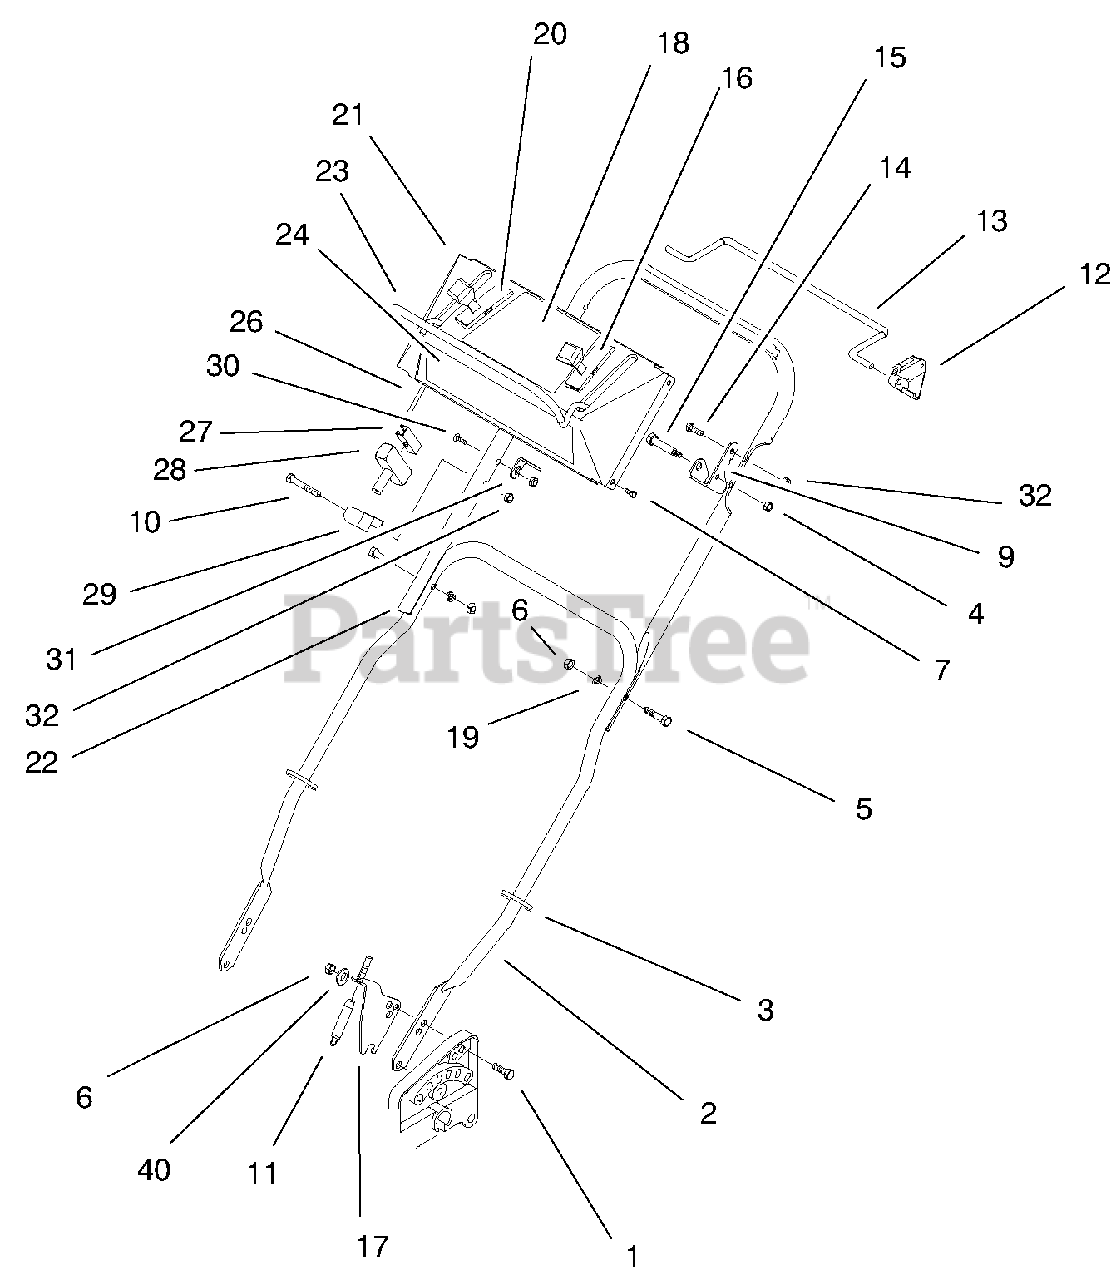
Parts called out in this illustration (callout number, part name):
1	Bolt-CARR
2	Handle Section-Lower
3	Tie Strap
4	Nut-Lock
5	Screw-HH
6	Nut-Lock
7	Screw-Phil
9	Bail Stop Bracket
10	Bolt-Hex
12	Stop-Pivot
13	Bail-Sp Control
14	Screw-HH
16	Throttle Cable
17	Bracket-Traction Cable
18	Decal-Control Panel
20	Control-Speed
21	Panel-Control
22	Handle-Upper
23	Engine Control Bail
24	Decal-Console
26	Cable-Control
27	Clip-Rope
28	Handle-Starter
29	Guide-Rope
30	Handle Screw
31	Bracket-Cable Anchor
32	Nut-Lock
40	Washer-Flat
